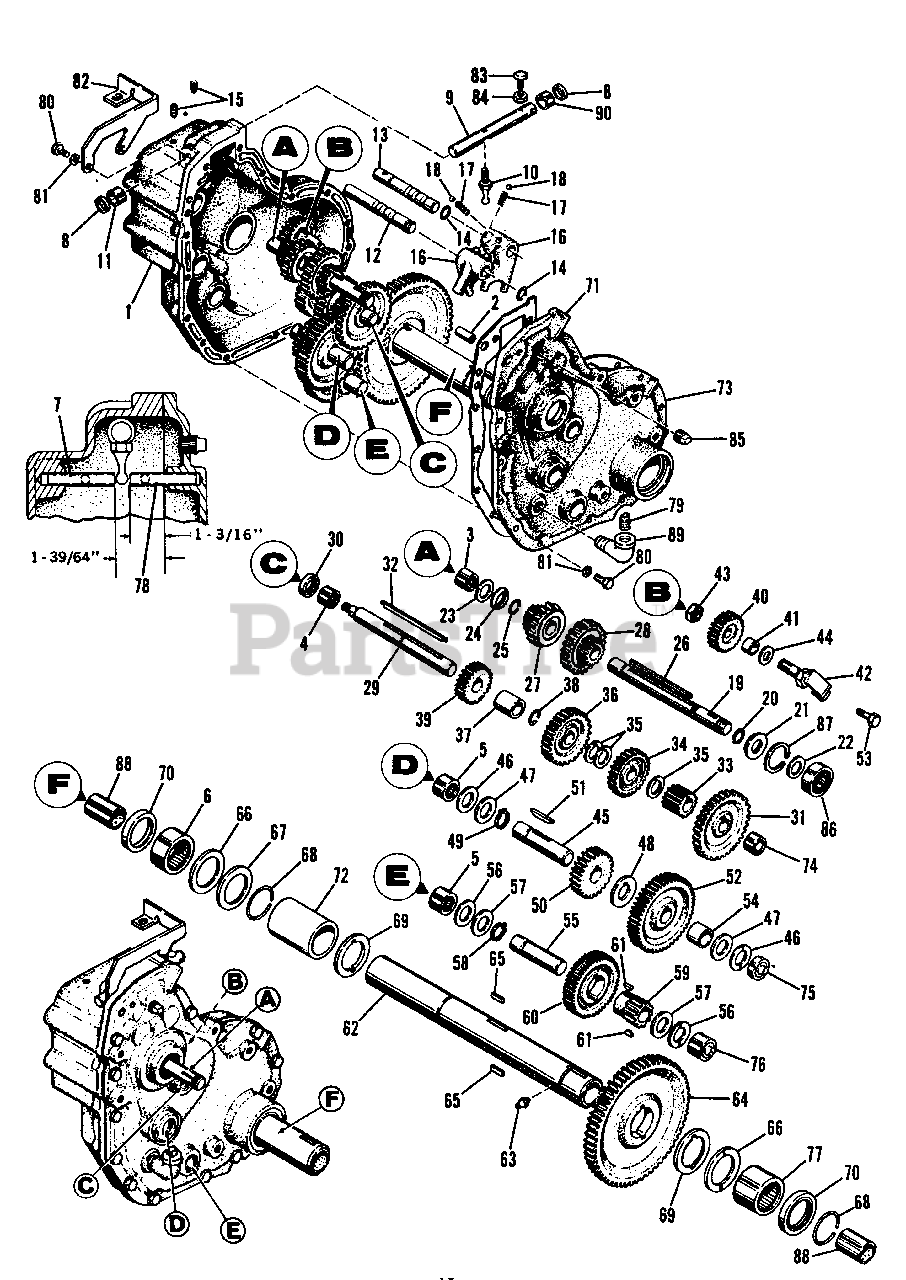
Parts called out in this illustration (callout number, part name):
1	GEAR CASE SUB ASSEMBLY W/BEARINGS (Includes 1 Thru 7)
2	PIN, Roll
3	BEARING, Needle
4	BEARING, Needle
5	BEARING, Needle
6	BEARING, Needle
7	ROLL PIN SUB ASSEMBLY
9	ROD, Shift
10	STEM, Shift
12	SHAFT, Shifter
13	SHAFT, Shifter, Hi-Lo
14	RING, Retaining
15	SCREW, Set, 5/16"-18 x 1/2" lg.
16	FORK, Shifter
18	BALL, Shift, Lock
19	SHAFT, Pulley
20	RING, Retaining
25	RING, Retaining
27	PINION ASSEMBLY, Rev II
28	PINION ASSEMBLY, I & II
29	SHAFT, 1st Intermediate
31	GEAR, Driven, I
33	PINION, 1st Intermediate
34	PINION, Driven, III
36	GEAR, Driven, II
38	RING, Retaining
39	PINION, Rev-IV
42	PIN ASSEMBLY, Rev. Gear
43	NUT, Hex, Full, Lock, 1/2"-20
45	SHAFT, II Intermediate
49	RING, Retaining
50	PINION, II Intermediate
52	GEAR, II Intermediate
53	CAPSCREW, Hex, 3/8-16 x 1-1/4" lg.
55	SHAFT, III Intermediate
58	RING, Retaining
59	PINION, III Intermediate
60	GEAR, III Intermediate
62	TUBE & BUSHING ASSEMBLY
63	FITTING, Lub.
64	GEAR, Drive
71	GASKET, Gear Case
73	COVER ASSEMBLY, Gear Case W/Bearings
74	BEARING, Needle
75	BEARING, Needle
76	BEARING, Needle
77	BEARING, Needle
78	ROLL PIN ASSEMBLY
79	PLUG, Pipe
80	CAPSCREW, Hex, 5/16"-18 x 1" lg.
81	LOCKWASHER, 5/16"
82	SUPPORT, Switch
83	BOLT, Carriage, 5/16"-18 x 1" lg.
84	NUT, Hex, Jam, 5/16-18
85	PLUG, Pipe
86	BEARING, Ball
87	RING, Retaining
89	ELBOW, 90ø
